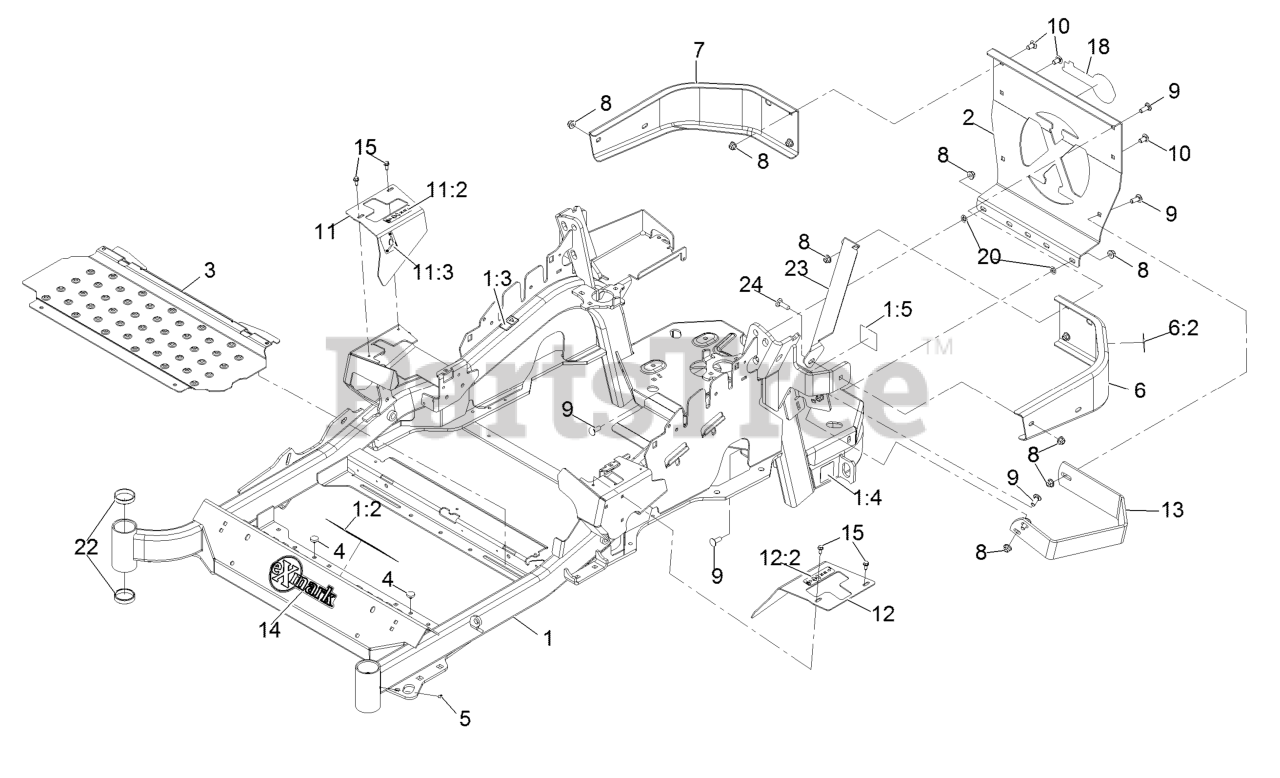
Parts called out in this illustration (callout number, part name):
1	Mainframe ASM
1:2	Decal-Danger
1:3	Decal-Warning
1:4	Decal-Hazard, Pinched Finger
1:5	Decal-Spark Arrester
2	Plate,Rear Guard
6	LH Bumper ASM
6:2	Decal-Warning
7	Bumper-RH
8	Nut-HF, NI
9	Screw-CARR
10	Screw-CARR
11	RH Motion Control Cover ASM
11:2	Decal-Control, Motion
11:3	Decal-Park Brake, CE
12	LH Motion Control Cover ASM
12:2	Decal-Control, Motion
13	Guard-Muffler
14	Decal-Exmark
15	Screw-HWH
18	Decal-Exmark Logo
20	Nut-Push
22	Cup-Bearing
24	Bolt-CARR
